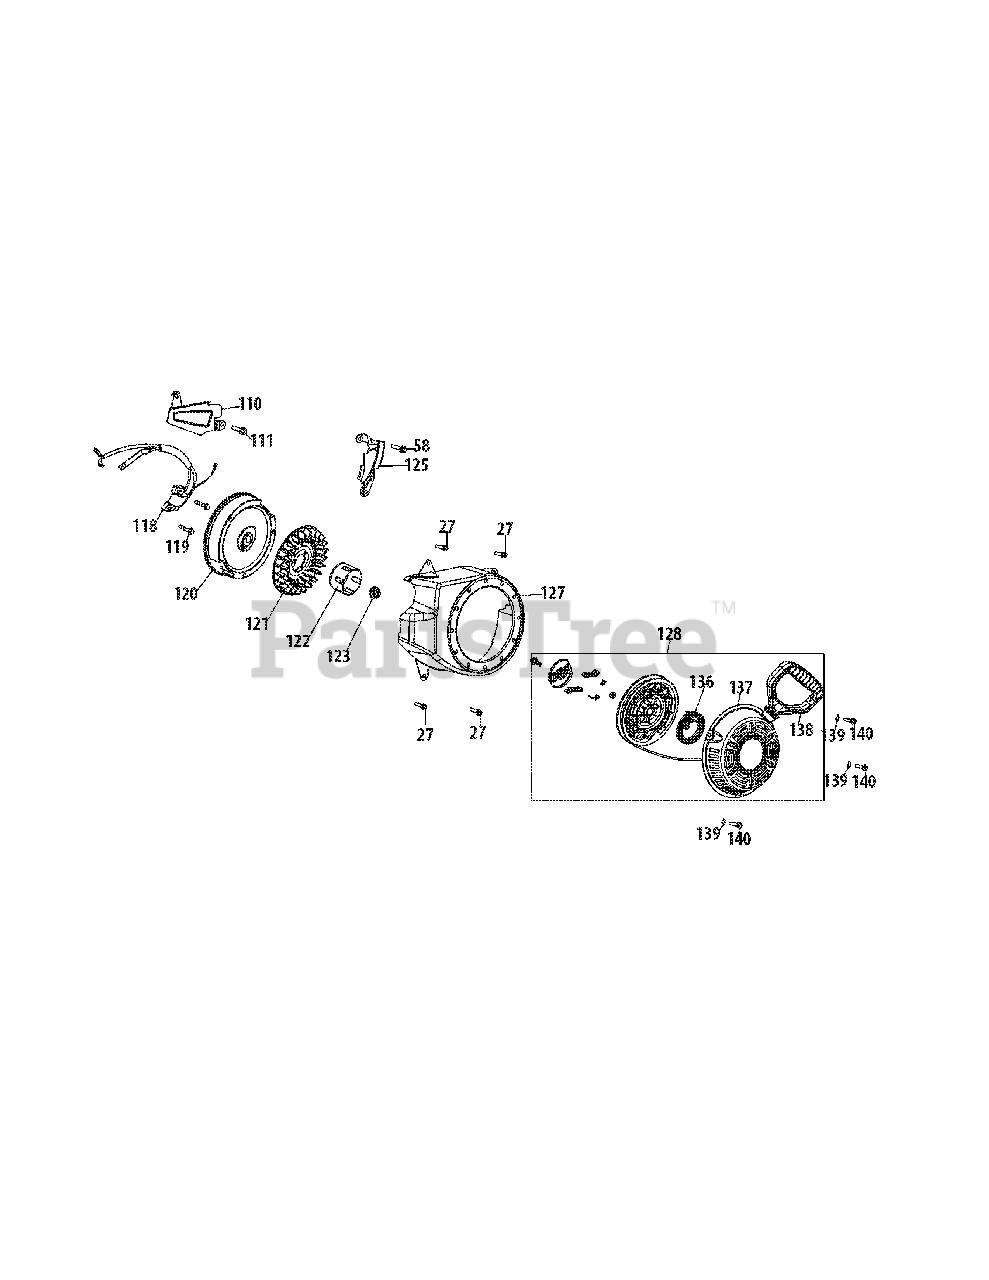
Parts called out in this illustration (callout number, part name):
27	BOLT M6×12
58	BOLT M6×12
111	BOLT M6×10
118	IGNITION MODULE
119	BOLT M6×25
120	FLYWHEEL
121	COOLING FAN
122	PULLEY, STARTER
123	FLANGE NUT M14×1.5
125	LOWER SHIELD
127	BLOWER HOUSING
128	RECOIL STARTER
136	RECOIL SPRING
137	BLOWER HOUSING
138	STARTER HANDLE
139	WASHER F6
140	BOLT M6×10
